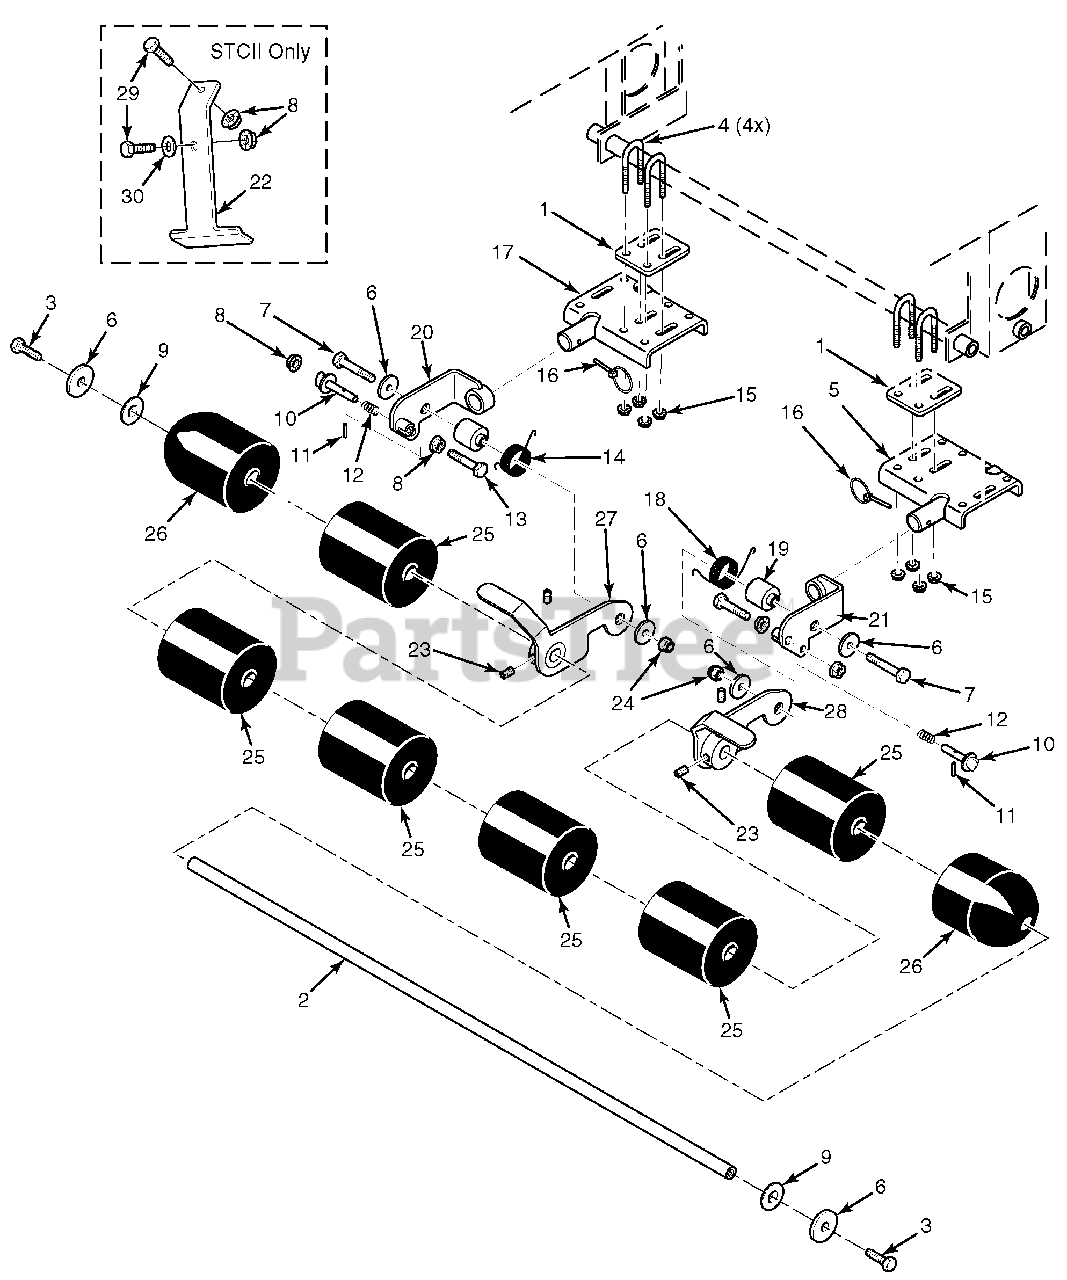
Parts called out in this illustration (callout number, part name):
1	Spacer, Striper Mounting
2	Roller Shaft
3	Bolt, Hex Head 3/8-16 x 1" (Special Lock)
4	U-Bolt, 5/16-18 x 1"
5	Mounting Bracket Weldment, LH.
6	Flatwasher, 3/8-.406 x 1-1/2" 7 Gauge
7	Bolt, Hex Head 3/8-16 x 2-3/4"
8	Nut, Serrated Flange 3/8-16
9	Flatwasher, 3/4-.812 x 1-3/8 x .100
10	Pin, Lift Latch
11	Pin, Slotted Spring .156 x 3/4"
12	Spring, Lock Pin
13	Bolt, Hex Head 3/8-16 x 2-1/2"
14	Spring, Torsion L.H.
15	Nut, Serrated Flange 5/16-18
16	Quick Pin, .188 Dia.
17	Mounting Bracket Weldment, R.H.
18	Spring, Torsion R.H.
19	Hub, Striper
20	Pivot Weldment, L.H.
21	Pivot Weldment, R.H.
22	Stop, Striper (STCII Only)
23	Set Screw, 3/8-16 x 1/2"
24	Nut, Elastic Stop 3/8-16
25	Wheel, Striper
26	Wheel, Striper End
27	Hinge Weldment, L.H.
28	Hinge Weldment, R.H.
29	Bolt, Hex Head 3/8-16 x 1-1/4"
30	Flatwasher, 3/8-.391 x .938 x .105
